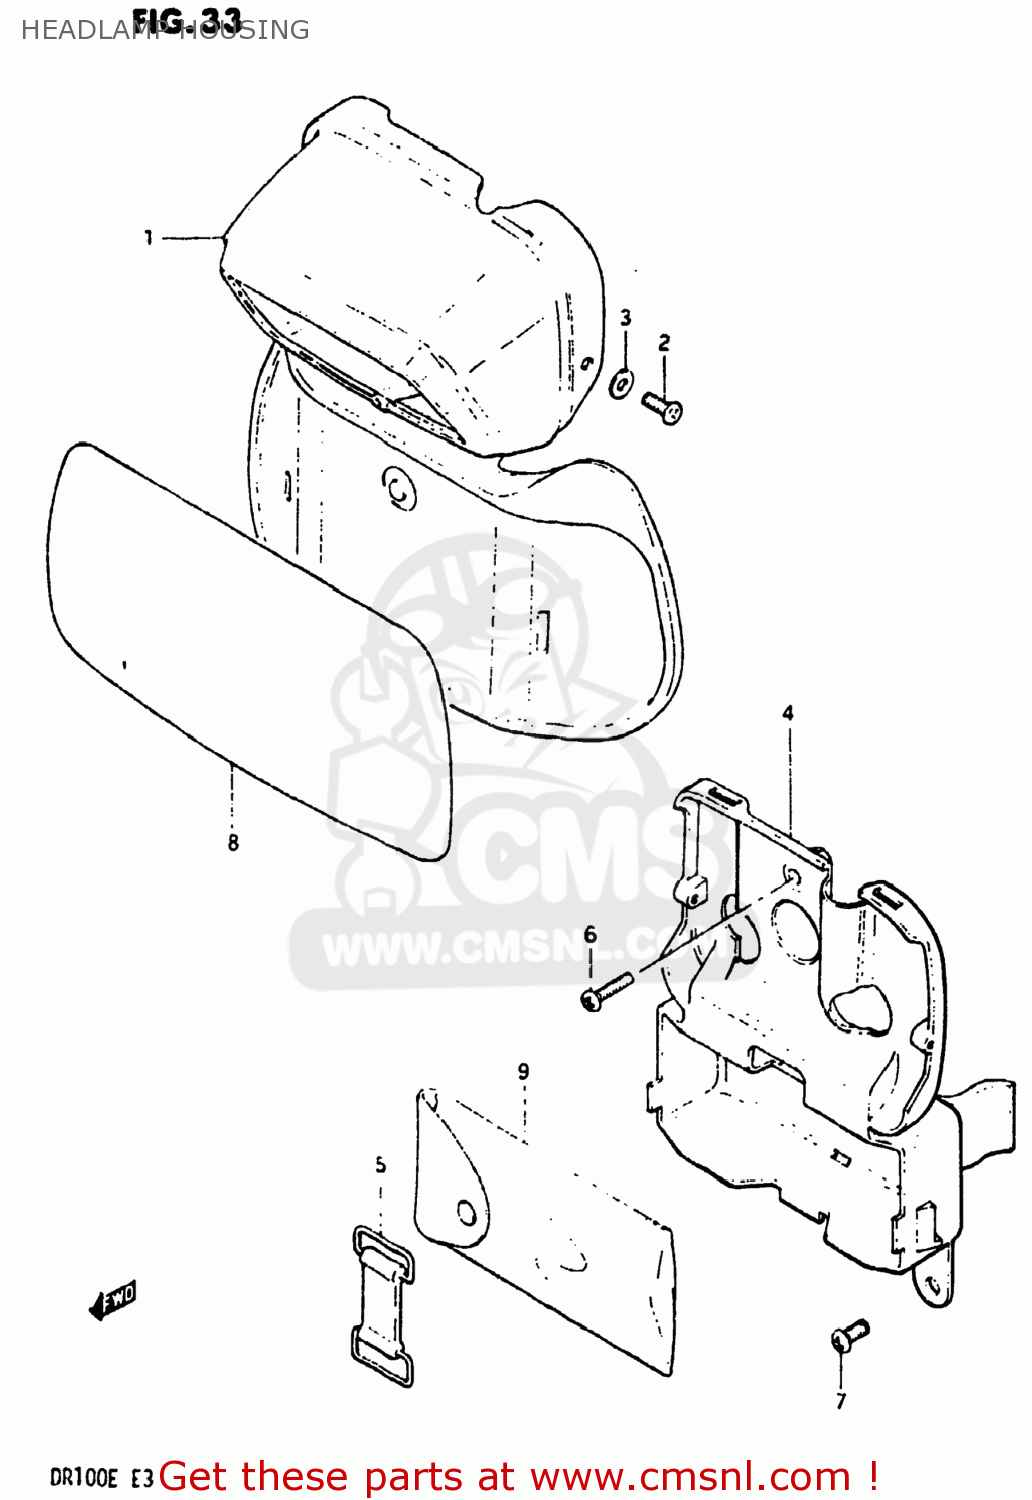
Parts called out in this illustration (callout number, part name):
1	HOUSING,HEADLAMP
2	TAPPING SCREW
3	WASHER
4	HOLDER,TOOL
5	BAND
6	(5X20) CROSS SCREW
7	SCREW
8	EMBLEM,FRONT NUMBER PLATE
9	TOOL SET
